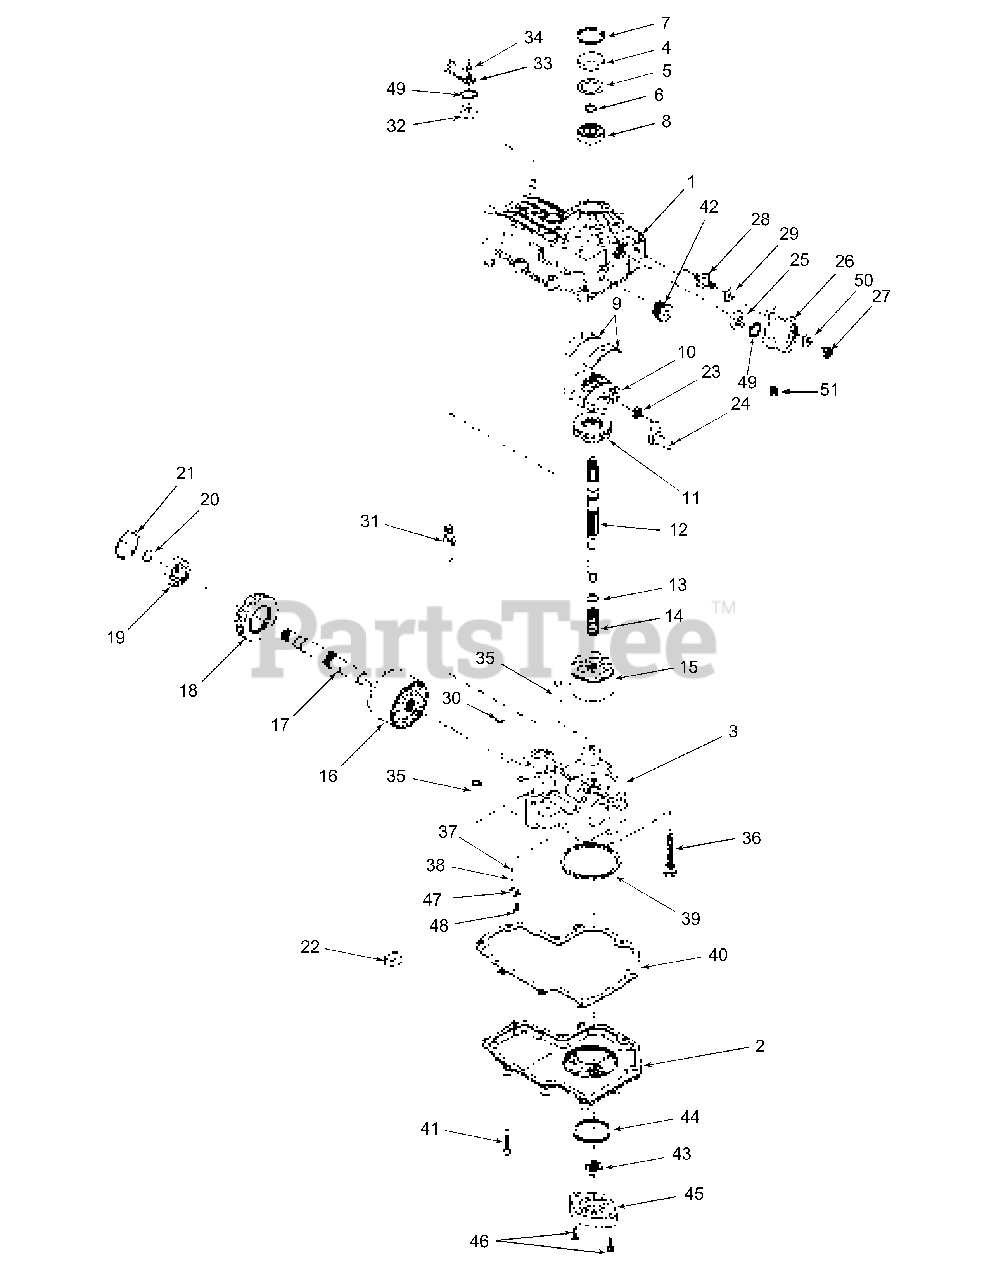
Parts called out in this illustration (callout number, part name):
1	Housing Ass’y Upper
2	Lower Housing
3	Center Section Assembly
6	Wire Retaining Ring
7	Retaining Ring
8	Ball Bearing
9	Cradle Bearing
10	Variable Swashplate
11	Thrust Bearing
13	Block Thrust Washer
15	Cylinder Block Assembly
16	Cylinder Block Assembly
17	Output Shaft (Motor)
18	Thrust Bearing
19	Ball Bearing
20	Wire Retaining Ring
21	Retaining Ring
22	Motor Bearing Retaining
27	Hex Lock Nut 5/16-24
28	Short Stud 5/16-24
29	Friction Puck
30	Bypass Plate
31	Bypass Actuator
34	Retaining Ring
37	Charge Relief Spring
41	Self Tapping Screw
43	Gerotor Assembly
45	Gerotor Cover
47	Relief Plate
49	Retaining Ring
